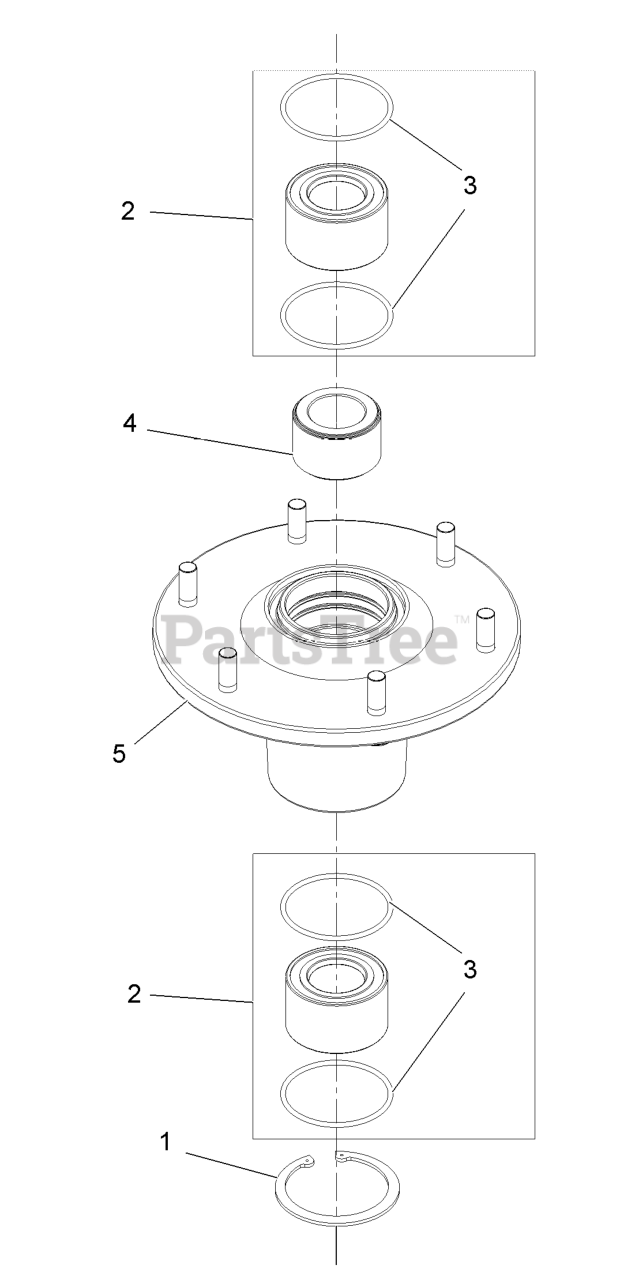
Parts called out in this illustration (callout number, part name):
1	RING-RETAINING
2	ASM, BEARING W/ORINGS
4	SPACER,BEARING
5	ASM,HOUSING W/STUDS
